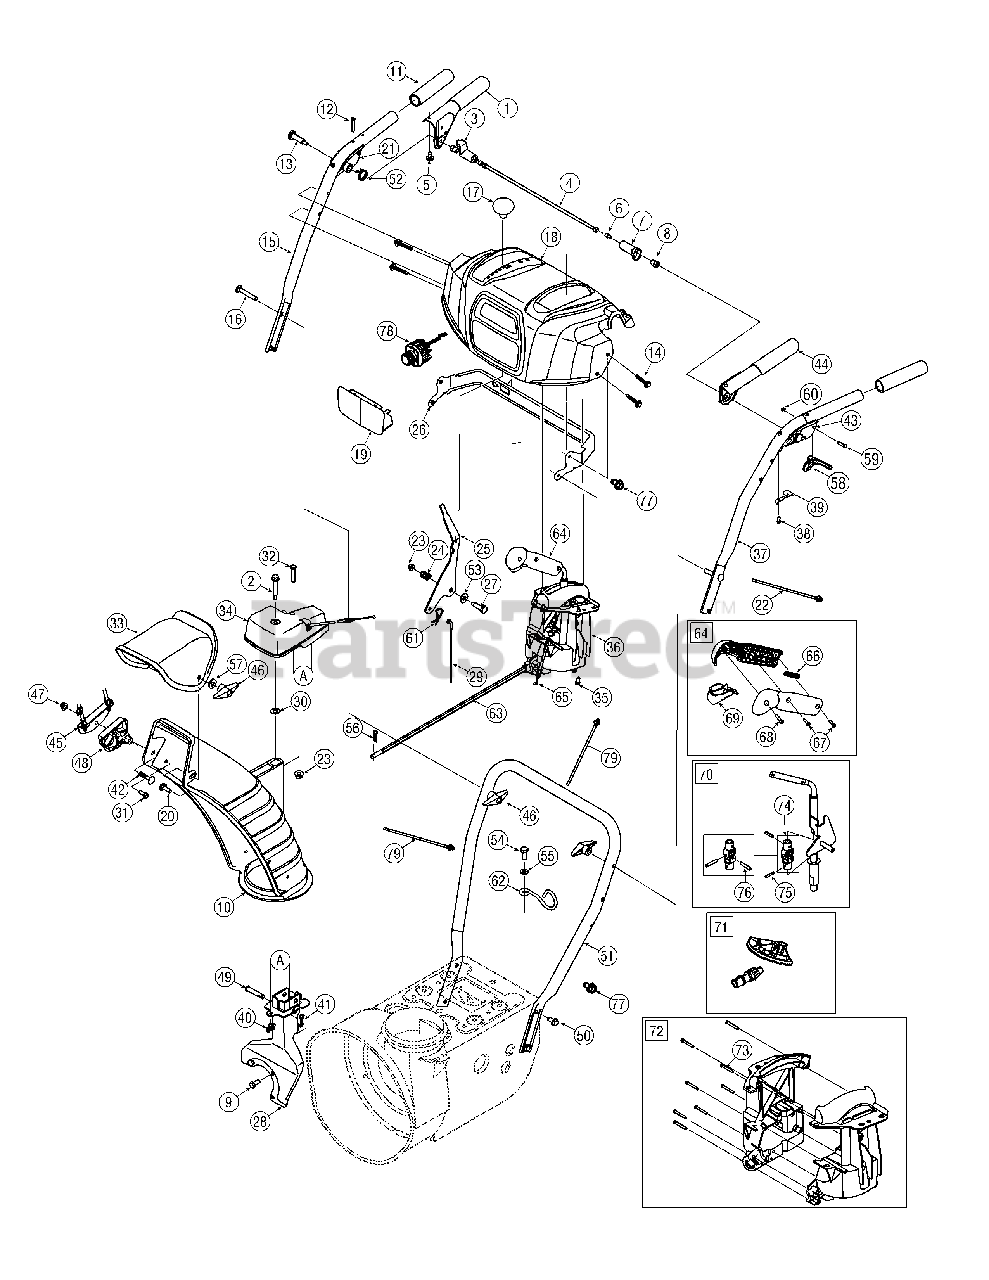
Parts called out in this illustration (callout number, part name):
1	Handle Engagement Assembly RH
2	Flange Shoulder Screw
3	Lock Plate
4	Pivot Rod
5	Rubber Bumper
6	Screw, 1/4-20 x .500
7	Clutch Lock Cam
8	Shoulder Nut, 1/4-20
9	Hex Screw, 5/16-24 x .750
10	Lower Chute
11	Handle Grip
12	Screw, #10-24 x 0.375
13	Shoulder Screw, 1/4-20
14	Screw, 1/4-20 x 1.625
15	Upper Handle RH
16	Carriage Screw, 5/16-18 x 2.25
17	Shift Knob
18	Handle Panel
20	Carriage Bolt, 5/16-18 x 1.0
21	Handle Clutch Lock RH Assembly
22	Cable Tie
23	Flange Lock Nut, 1/4-20
24	Compression Spring
25	Shift Lever
26	Panel Bracket
27	Shoulder Screw
28	Chute Support Bracket
29	Speed Selector Cable
30	Flat Washer, .25 x .630 x .0515
31	Hi-Lo Screw, 1/4-15 x .75
32	Hex Screw, 1/4-20 x 3.00
33	Upper Chute
34	4-Way Chute Gearbox Assembly
35	Hi-Lo Screw, 1/4-15 x 0.5
36	4-Way Chute Control™ Assembly
37	Upper Handle LH
38	Screw, #8-16 x 0.50
39	Clutch Lock Spring
40	Wing Nut, 1/4-20
41	Bow Tie Cotter Pin
42	Carriage Bolt, 5/16-18 x 1.50
43	Handle Clutch Lock LH Assembly
44	Handle Engagement Assembly LH
45	Cable Bracket
46	Wing Knob
47	Flange Lock Nut, 5/16-18
48	Chute Tilt Cable Guide
49	Clevis Pin
50	Screw, 5/16-18 x 0.75
51	Lower Handle
52	Torsion Spring
53	Flat Washer
54	Screw, M8-1.25
55	Flat Washer, .330 x .630 x .0635
56	Cotter Pin
57	Flat Washer, .349 x .879 x .063
58	Steering Control
59	Pin, 3/16
60	E-Ring
61	Click Pin
62	Cable Control Wire
63	Chute Rod
64	Handle Assembly
65	4-Way Cable
66	Handle Plunger
67	Screw, Mach., #8-32 x .750
68	Screw, #8 x 1.00
69	Handle Lever
70	Shift Assembly
71	Gear Set Assembly
72	Handle Housing Assembly
73	Screw, #8-18 x 1.250
74	Joint Block Assembly
76	Roll Pin
77	Scr., 1/4-20 x .500 (For Ground Wire)
78	LED Headlight
79	Cable Tie
